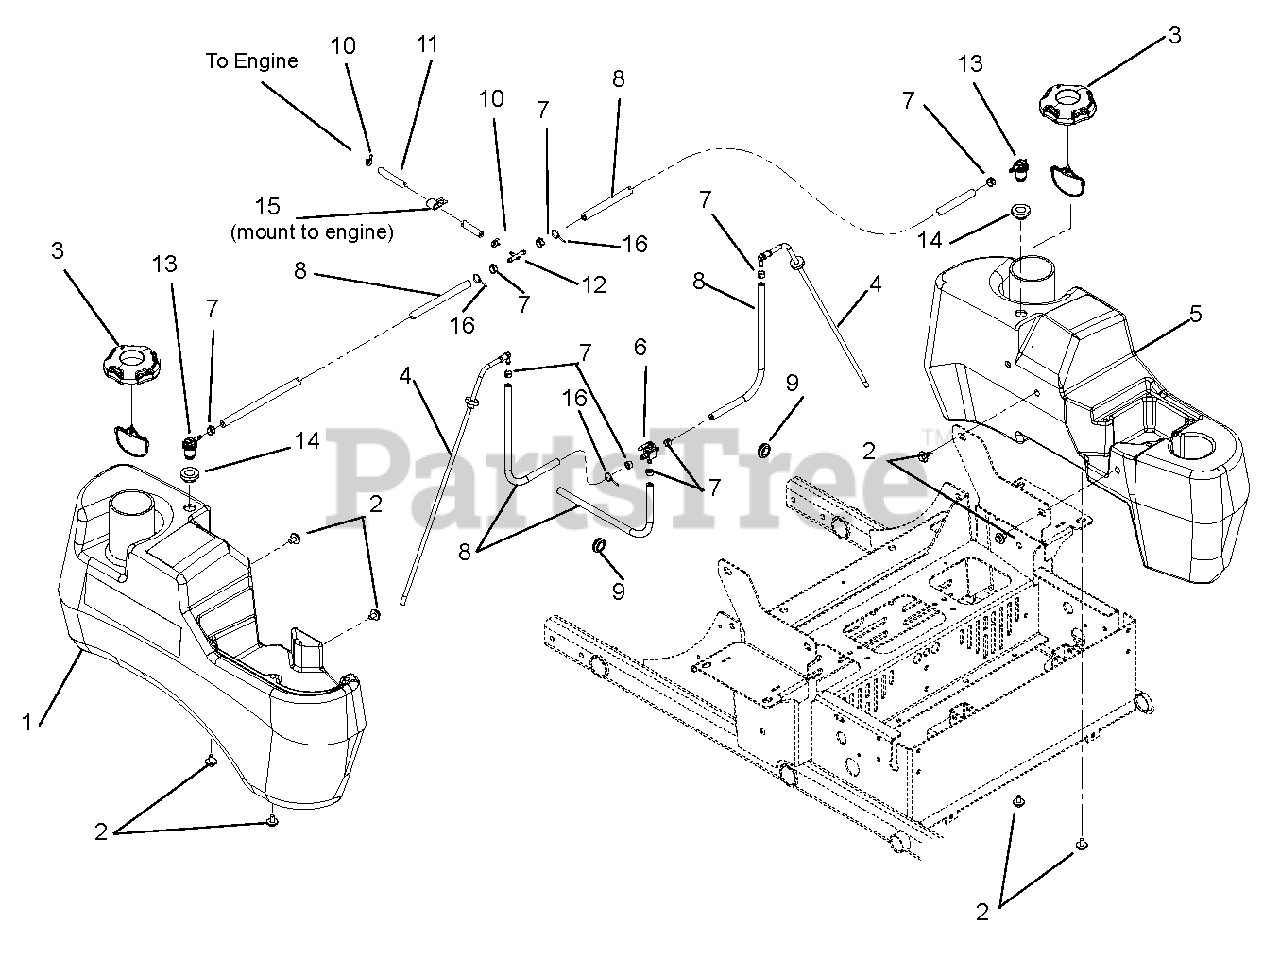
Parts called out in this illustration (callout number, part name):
1	Tank, Right Hand Fuel
2	Bolt, SEMS .31-18 x .62
3	Cap, Fuel, EPA
4	Assembly, Large Tank Fuel Pick-Up
5	Tank, Left Hand Fuel
6	Valve, Fuel
7	Clamp, Fuel Line
8	Hose, .25 Low-PERM Bulk Gas
9	Grommet, Rubber 5/8 ID/1.13 OD
10	Clamp, Hose, Spring .188
11	Hose, .188 Low-PERM Bulk Gas
12	Tee, 1/4HS Run x 3/16HS Branch
13	Valve, Combination
14	Grommet, Remote Vent Nitrile
16	Cable Tie with Tree (.25 hole)
